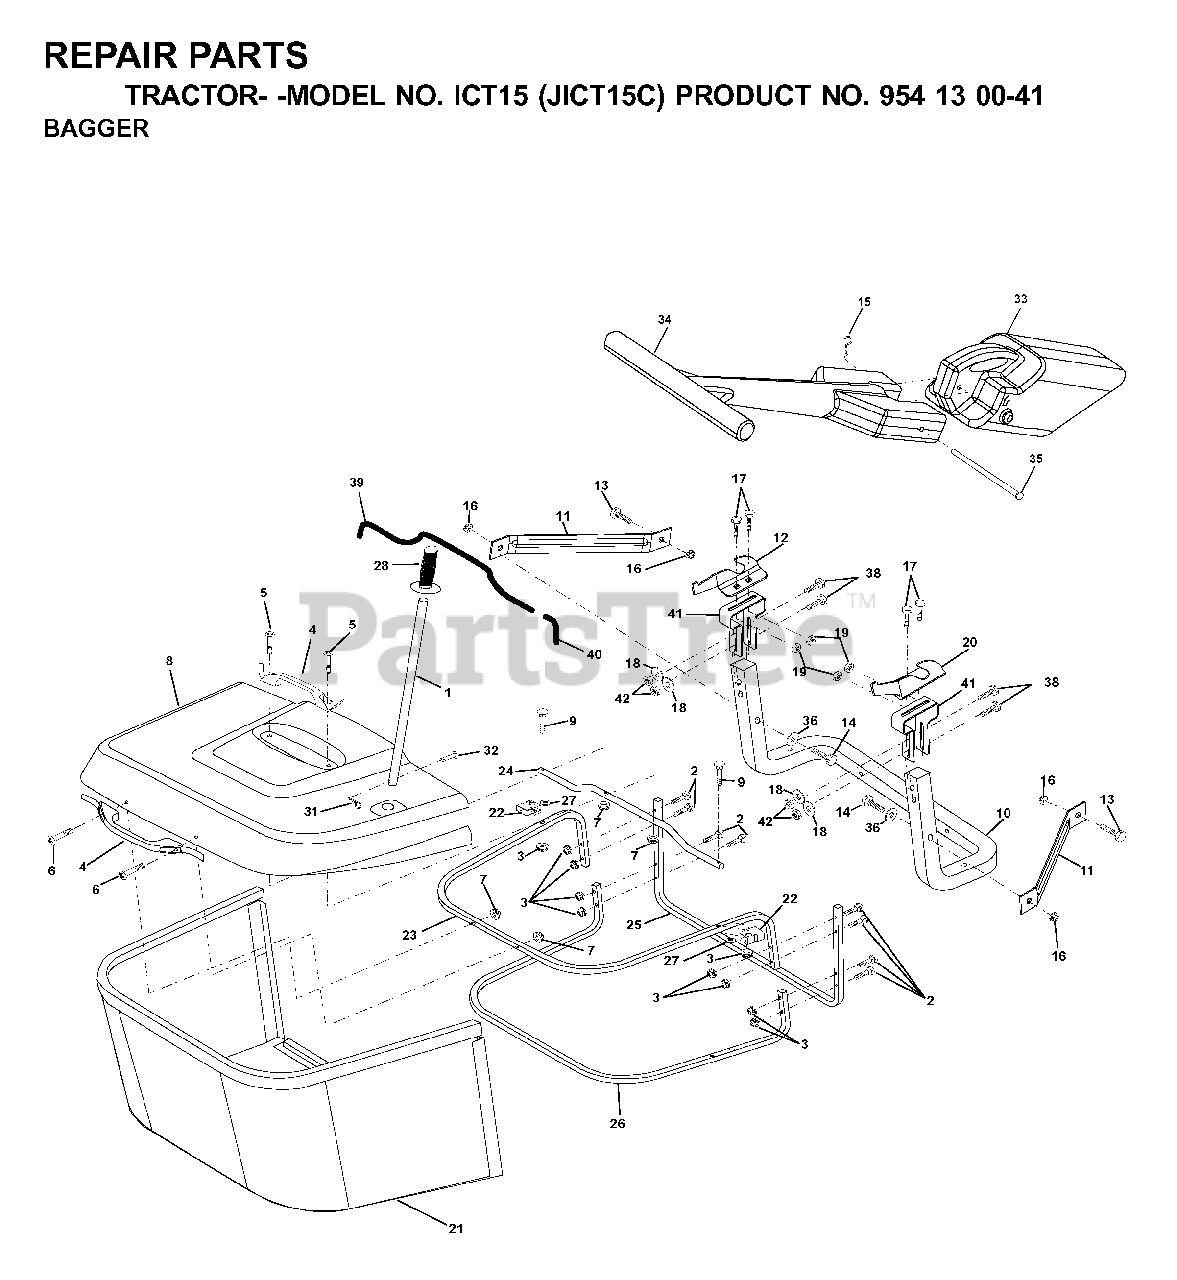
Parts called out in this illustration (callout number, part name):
1	TUBE HANDLE BAGGER
3	NUT T
5	SCREW.PAN.HEAD
10	TUBE
11	BRACKET
13	BOLT
15	RETAINER-SPRNG RB
16	NUT LOCK FLG 3/8-16 UNC
17	BOLT
18	WASHER M
19	NUT LOCK HEX FLANGE 5/16-18
20	BRACKET
21	BAG
22	BRACKET
23	TUBE
24	TUBE
26	TUBE
31	RETAINER M
32	RIVET,DRILLED
33	MULCH PLUG, CTH150
35	PIN
36	WASHER
38	BOLT.5/16-18X2.5
39	TRIM
40	TRIM
41	BRKT, BAGGER
42	NUT.71038.31-18.HEX.NYLOCK
